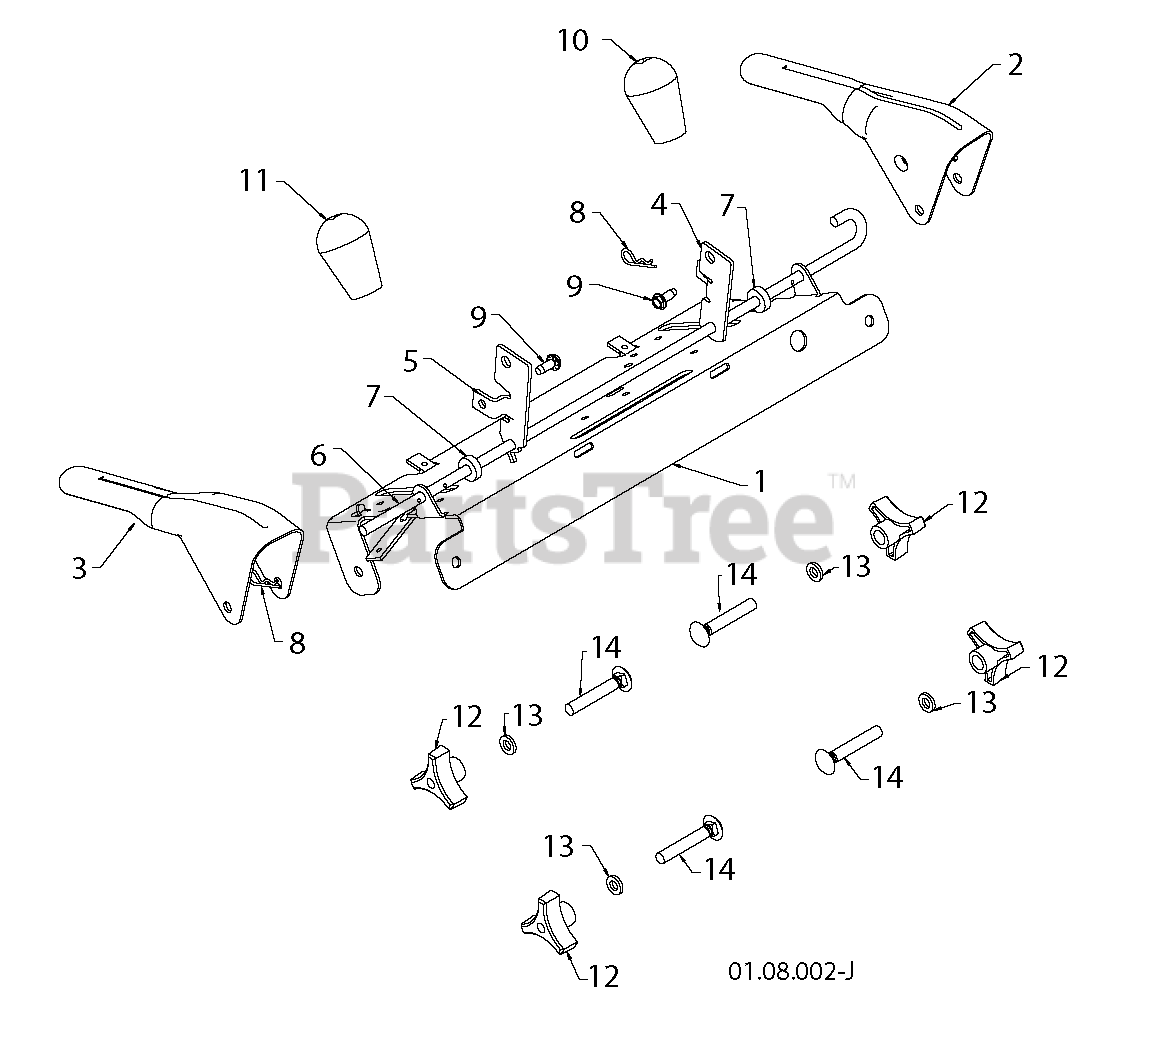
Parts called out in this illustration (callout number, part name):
1	PANEL.CONTROL.PNT.BLACK
2	LEVER.CONTROL.LH.BLACK
3	LEVER.CONTROL.RH.PNT.BLACK
4	ARM.TRACTION.ROD.YZ
5	ARM.IMPELLER.ROD.
6	BAIL.CONTROL.INTERLOCK
7	SPACER.CONTROL.LEVER
8	SPRING RETAINER
9	SCREW 14-20 X 5/8
10	KNOB LEVER, BLACK
11	RED KNOB SHIFTER
12	KNOB.HANDLE.3/8.TRI-POINT.BLAC
14	BOLT 3/8-16 X 2-1/4
